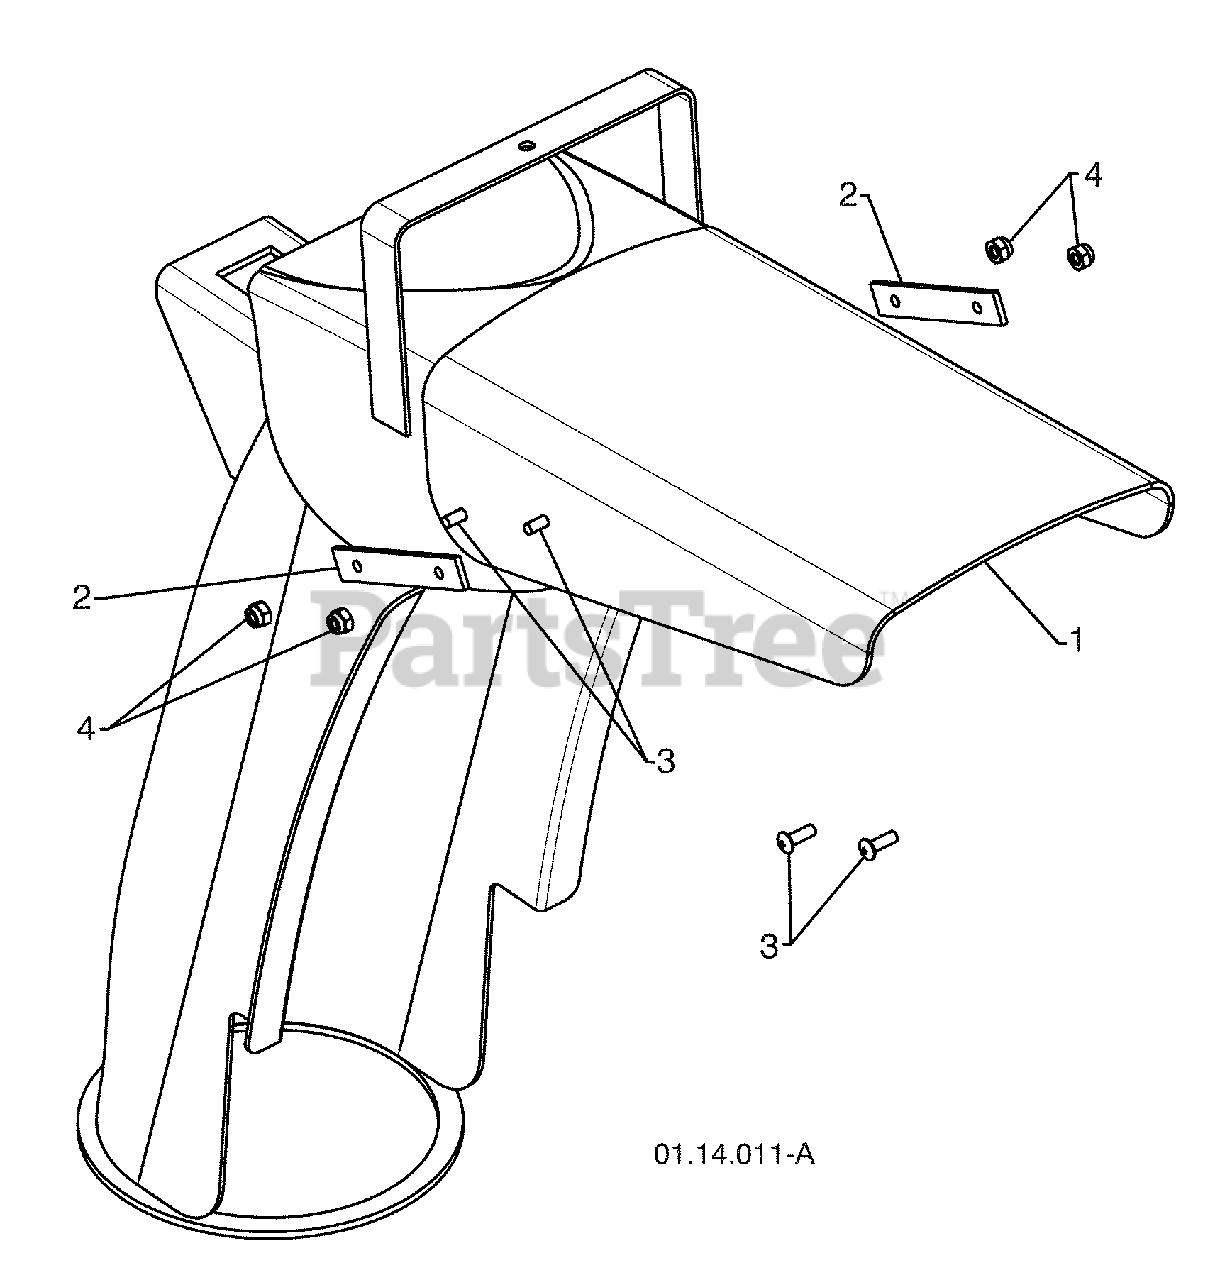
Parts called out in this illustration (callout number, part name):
1	SHIELD DEFLECTOR
2	STRAP
3	SCREW 8-32 X .50
